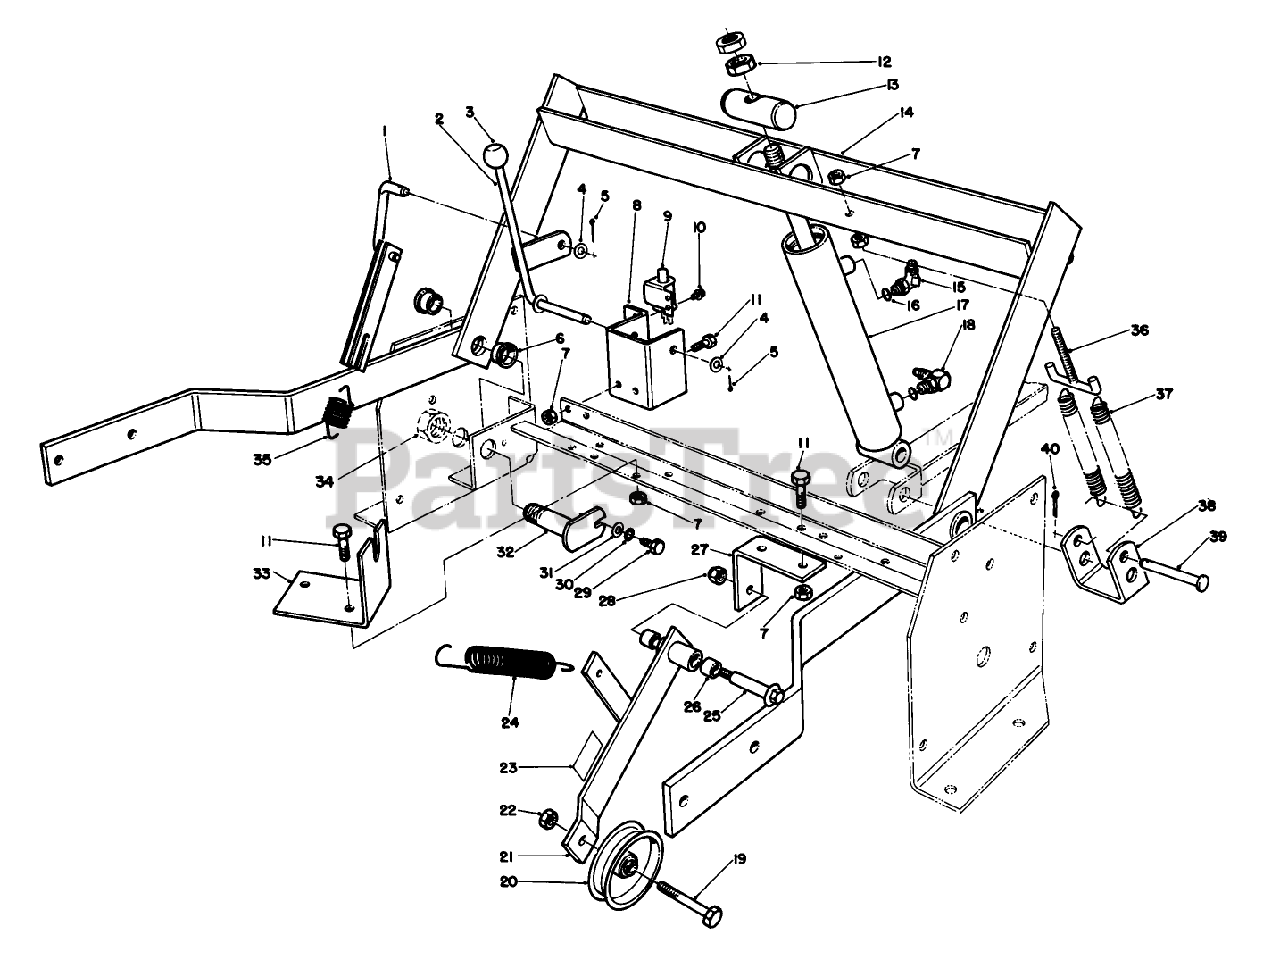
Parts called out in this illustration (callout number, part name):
4	WASHER-FLAT
5	PIN-COTTER
6	BEARING-FLANGE
7	NUT-LOCK, NI
9	SWITCH-BRAKE, PARKING
10	SCREW-TAPTITE
11	SCREW-HH
12	NUT-JAM
13	CYL.PIVOT PIN
15	FITTING-45 DEG
16	O-RING
17	CYLINDER - LIFT
18	FITTING-ELBOW, 90
19	SCREW-HH
21	IDLER LEVER ASM
22	NUT-LOCK, NI
23	DECAL-WARNING
24	IDLER EXT SPRING
25	BOLT-WHEEL
26	BUSHING
27	JACKSHFT IDLR BRKT
28	NUT-LOCK
29	SCREW-HH
30	WASHER-LOCK
31	WASHER-FLAT
33	TRACT CABLE BRKT
34	NUT-LOCK, NI
35	PARK BRAKE SPRING
36	T-HOOK W A
38	SPRING BRACKET
39	PIN-CLEVIS
40	PIN-HAIR
